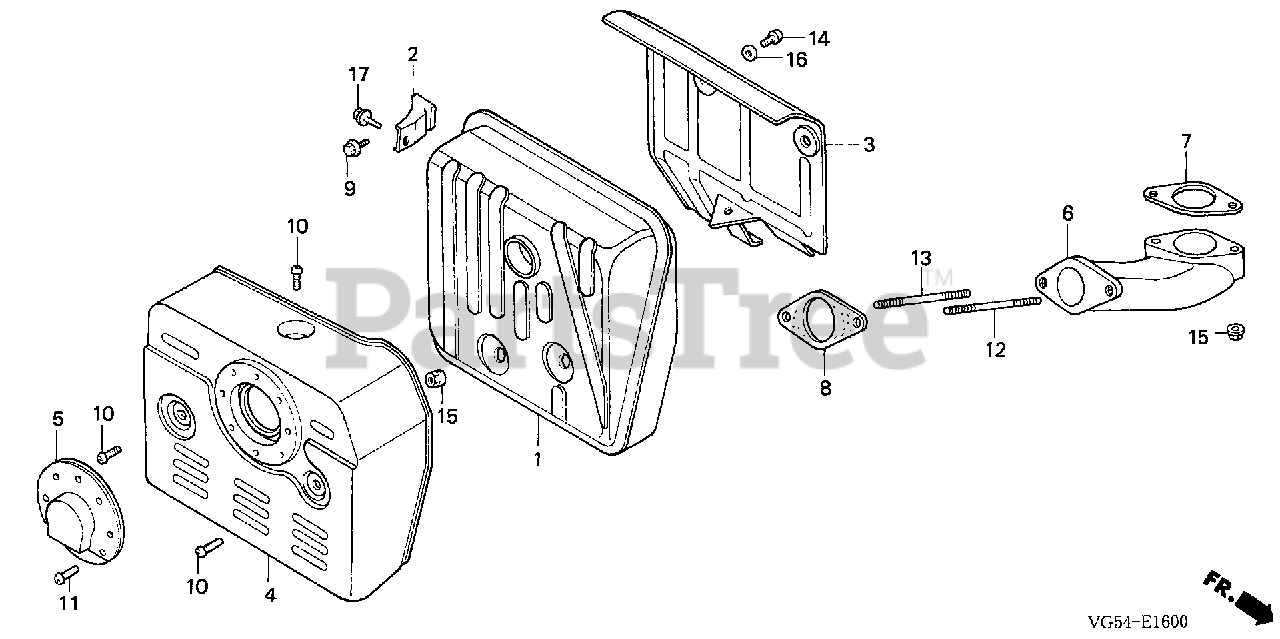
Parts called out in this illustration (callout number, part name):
2	SEPARATOR, MUFFLER
3	STAY, MUFFLER
4	PROTECTOR, MUFFLER
5	CAP, MUFFLER
7	GASKET, EX. PIPE
7	GASKET, EX. PIPE (WACKER)
8	GASKET, EX. PIPE
9	BOLT, FLANGE (8X16)
10	SCREW, TAPPING (5X8)
11	SCREW, TAPPING (4X6)
12	BOLT, STUD (8X60)
13	BOLT, STUD (8X70)
14	SCREW, PAN (6X6)
15	NUT, FLANGE (8MM)
16	WASHER, PLAIN (6MM)
17	BOLT, FLANGE (8X14)
